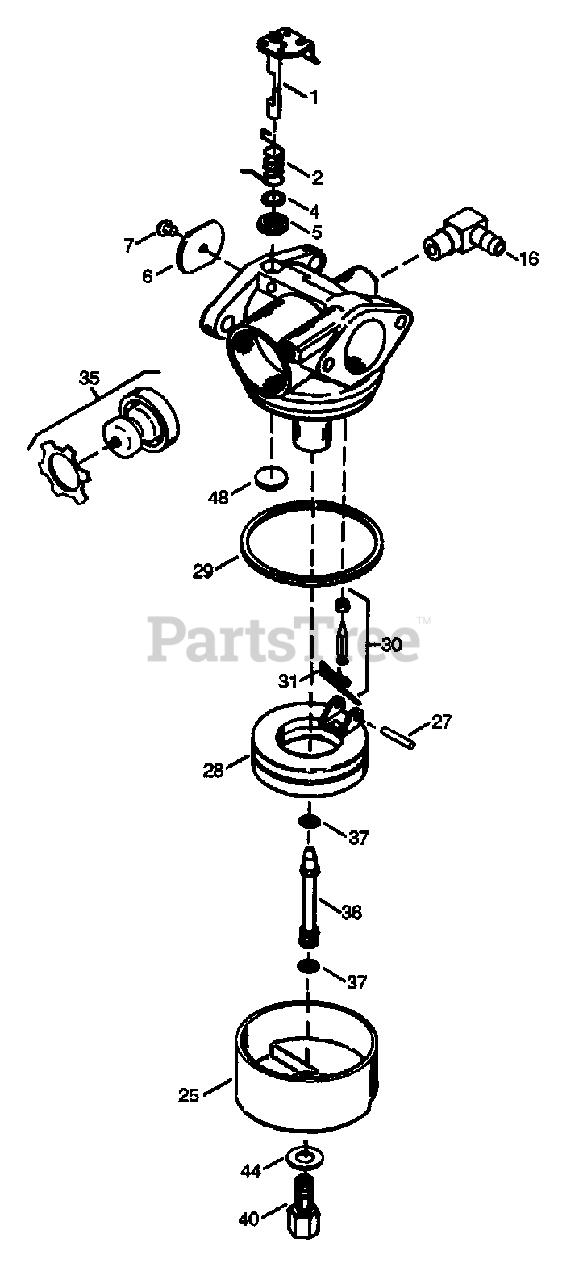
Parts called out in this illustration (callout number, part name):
1	Throttle Shaft & Lever Assembly
2	Throttle Return Spring
4	Dust Seal Washer
5	Dust Seal (Throttle)
6	Throttle Shutter
7	Shutter Screw
16	Fuel Fitting
25	Float Bowl
27	Float Shaft
29	Float Bowl "O" Ring
30	Inlet Needle, Seat, & Clip (Incl. 31)
31	Spring Clip
35	Primer Bulb/Retainer Ring
36	Main Nozzle Tube
37	O-Ring, Main Nozzle Tube
40	High Speed Bowl Nut
44	Bowl Nut Washer
48	Welch Plug, Atmospheric Vent
